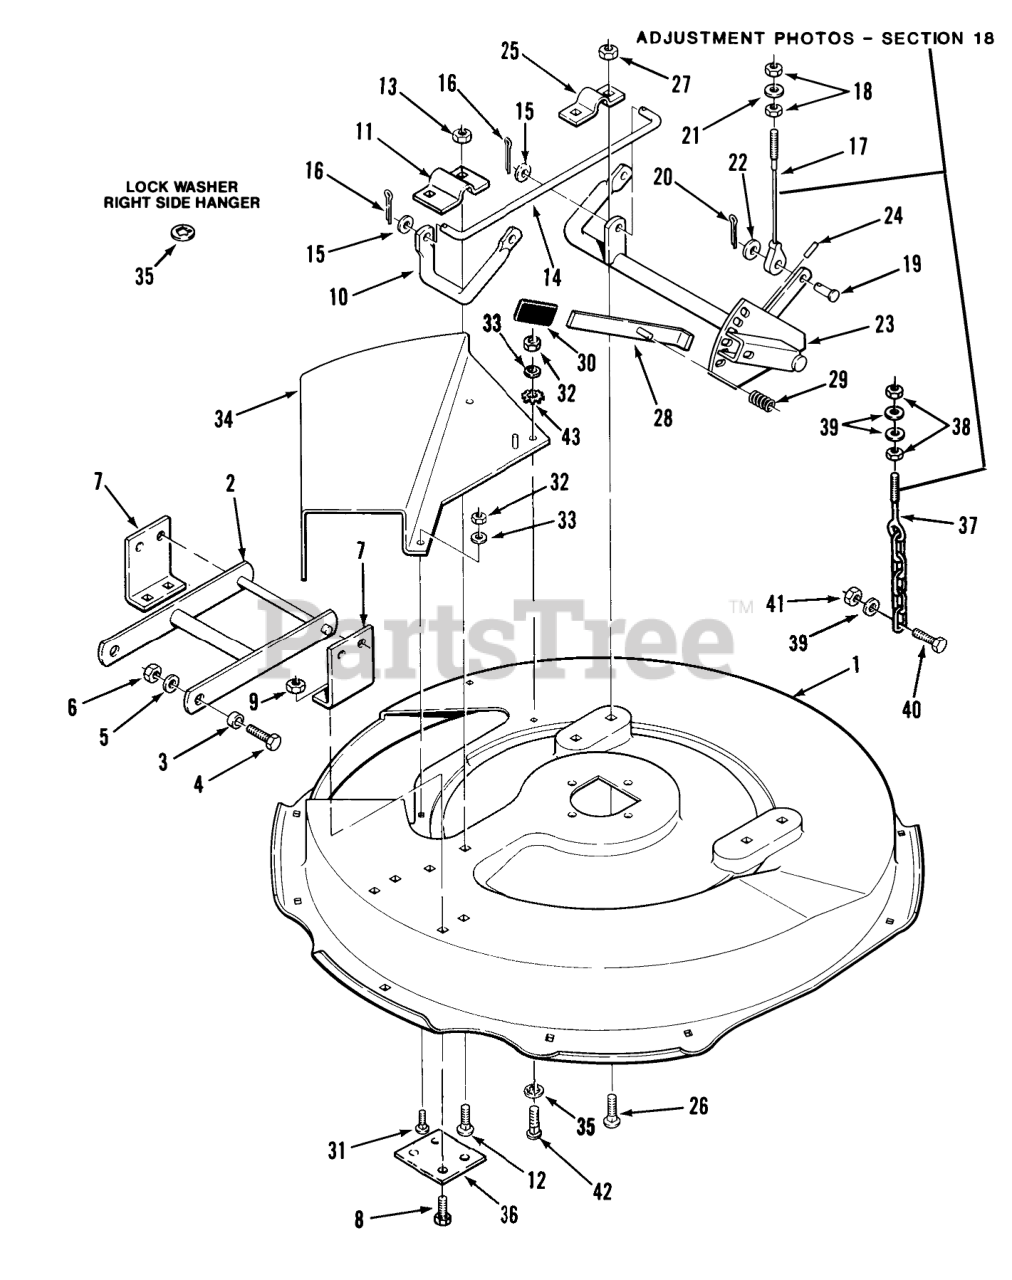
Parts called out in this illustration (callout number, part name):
1	DECK 30" MOWER R
2	ASSY MWR FRONT MO R
3	SPACER
4	BOLT
5	Washer
6	NUT
7	BRKT FRONT MOWER R
8	BOLT
9	NUT
10	ROD HEIGHT ADJ R
11	CLAMP B
12	Bolt
13	NUT
14	ROD HEIGHT ADJUST
15	Washer
16	Cotter Pin
17	CABLE MOWER SUPPORT
18	Nut
19	CLEVIS PIN
20	Cotter Pin
21	WASHER 5/16 SAE
22	Washer
23	HEIGHT ADJ ASSY R
24	SPIROL PIN
26	Bolt
27	NUT
28	LEVER ASSY
29	SPRING-COMPRESSION
31	Bolt 1/4-20 X 5/8
32	Nut
34	Mower Deflector
35	Washer-Lock
36	PLATE-BACKUP R
37	CHAIN-SUPPORT
38	Nut
39	WASHER 5/16 SAE
40	Nut
41	Bolt
42	Bolt-Carriage
43	LOCKWASHER
